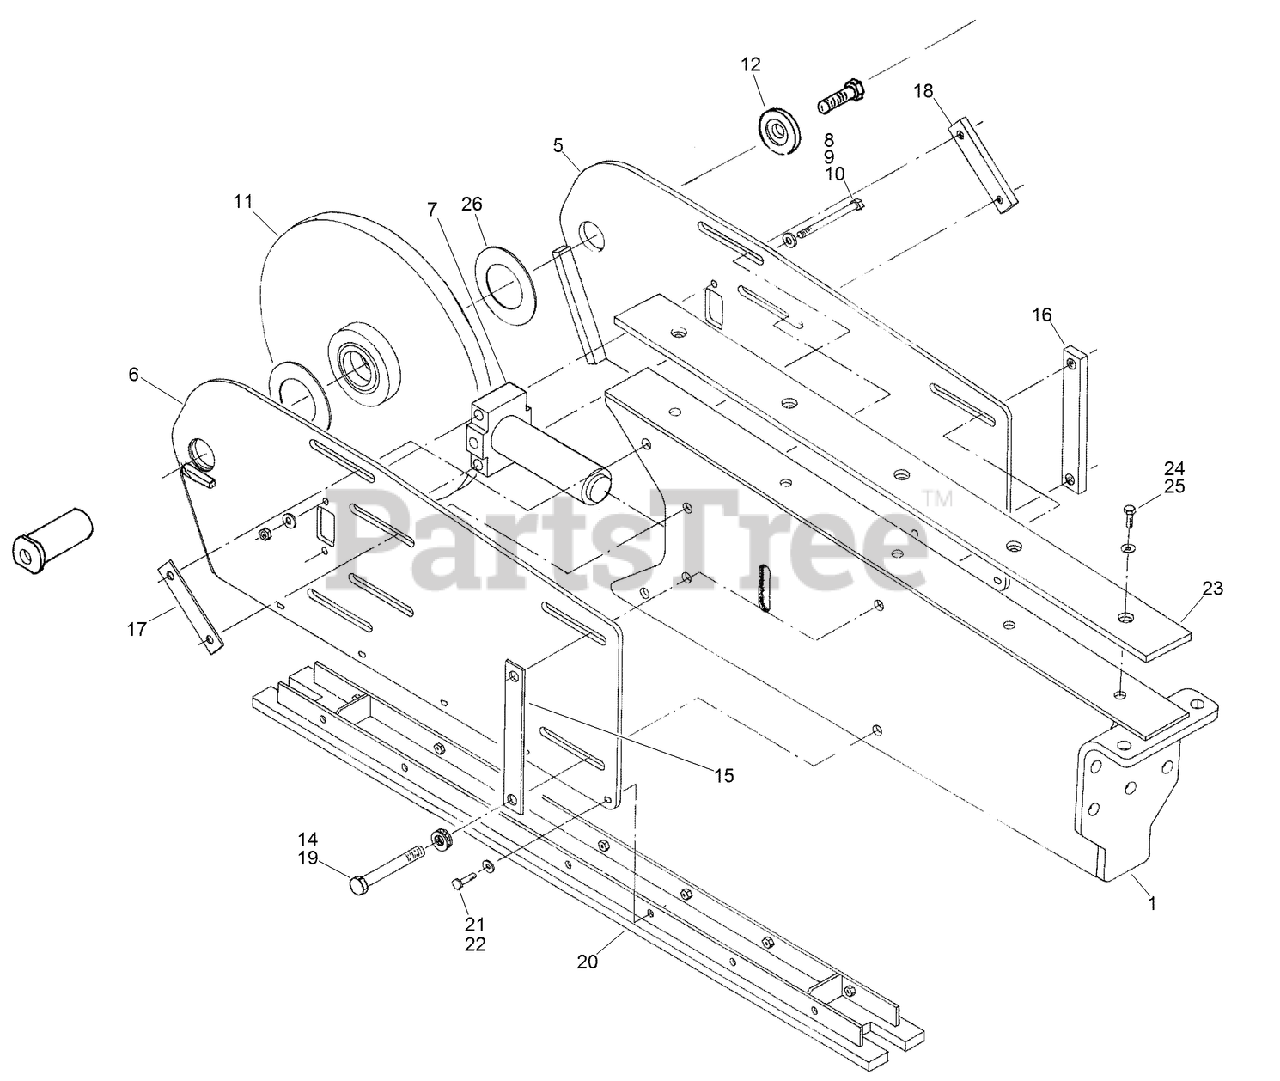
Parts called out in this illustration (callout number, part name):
1	ASSEMBLY - Rock Boom, 5 Ft
5	PLATE - Left Hand
6	PLATE - Right Hand
7	ASSEMBLY - Adjuster, Rock Boom
9	NUT-HEX
11	BOOM END ASM
12	WASHER-BOOM, END (ROLLER)
15	BAR-WASHER, LONG
16	BAR-TAPPED, LONG
17	BAR-WASHER, SHORT
18	BAR-TAPPED, SHORT
19	WASHER-LOCK
20	CHANNEL - Lower
21	BOLT
22	WASHER-FLAT
23	PAD - Wear
24	SCREW-HH
25	WASHER-Spring Lock, Reg 3/8 ZND
